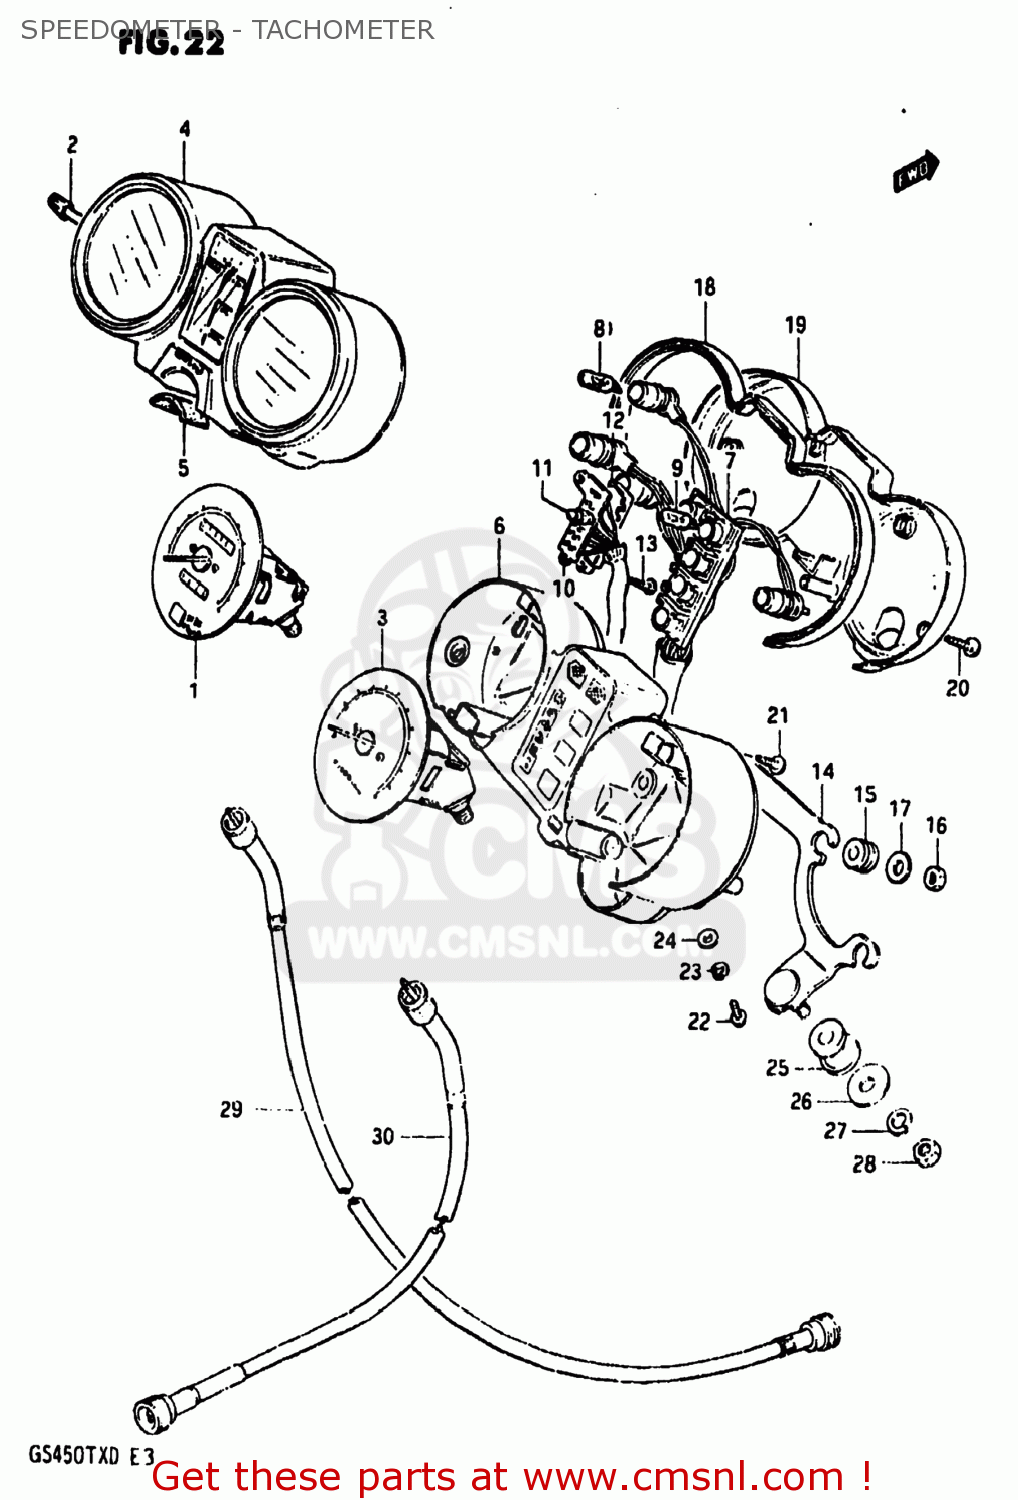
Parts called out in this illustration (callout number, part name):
1	METER,SPEEDOMETER (KM/MPH)
2	KNOB
3	TACHOMETER
4	HOOD,METER
5	SEAL,IGNITION SWITCH
6	CASE,METER,INNER
8	BULB(12V3.4W,T10)
9	BULB(12V1.7W,T10,WB121)
10	SOCKET,GEAR INDICATOR
11	BULB(14V1.12W,BQ041-32503B)
12	COVER,INDICATOR,LOWER
13	SCREW
14	BRACKET,COMBINATION METER
15	CUSHION,METER
16	NUT
17	WASHER (5.5X16X1.2)
18	COVER,METER,UNDER
19	COVER,LWR
20	SCREW
21	SCREW
22	SCREW 4X10
23	WASHER
24	LOCK WASHER
25	CUSHION,METER BRACKET
26	WASHER (8.5X29X1.6)
27	LOCK WASHER
28	NUT
29	CABLE ASSEMBLY,SPEEDOMETER
30	CABLE ASSEMBLY,TACHOMETER
